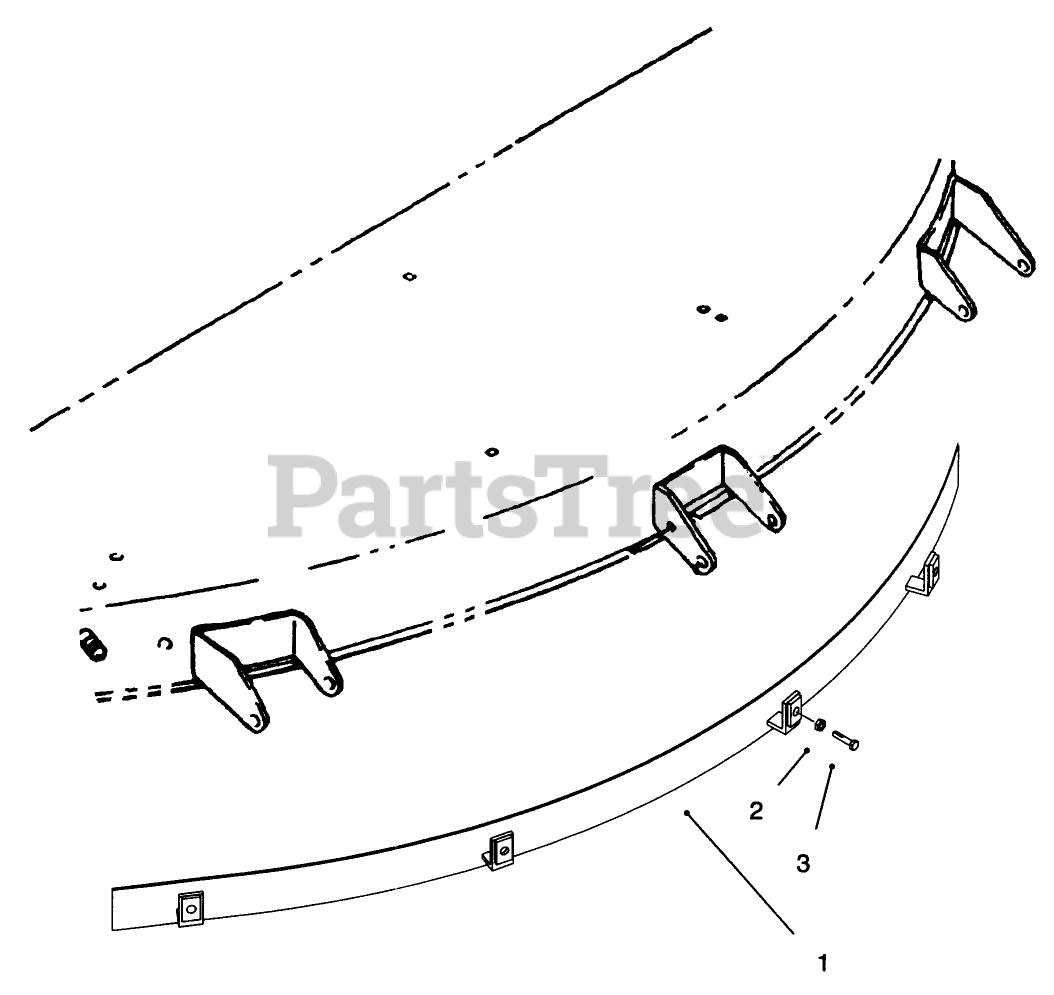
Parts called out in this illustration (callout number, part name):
1	Front Shield-42"
2	NUT-JAM
3	SCREW - HHCS
